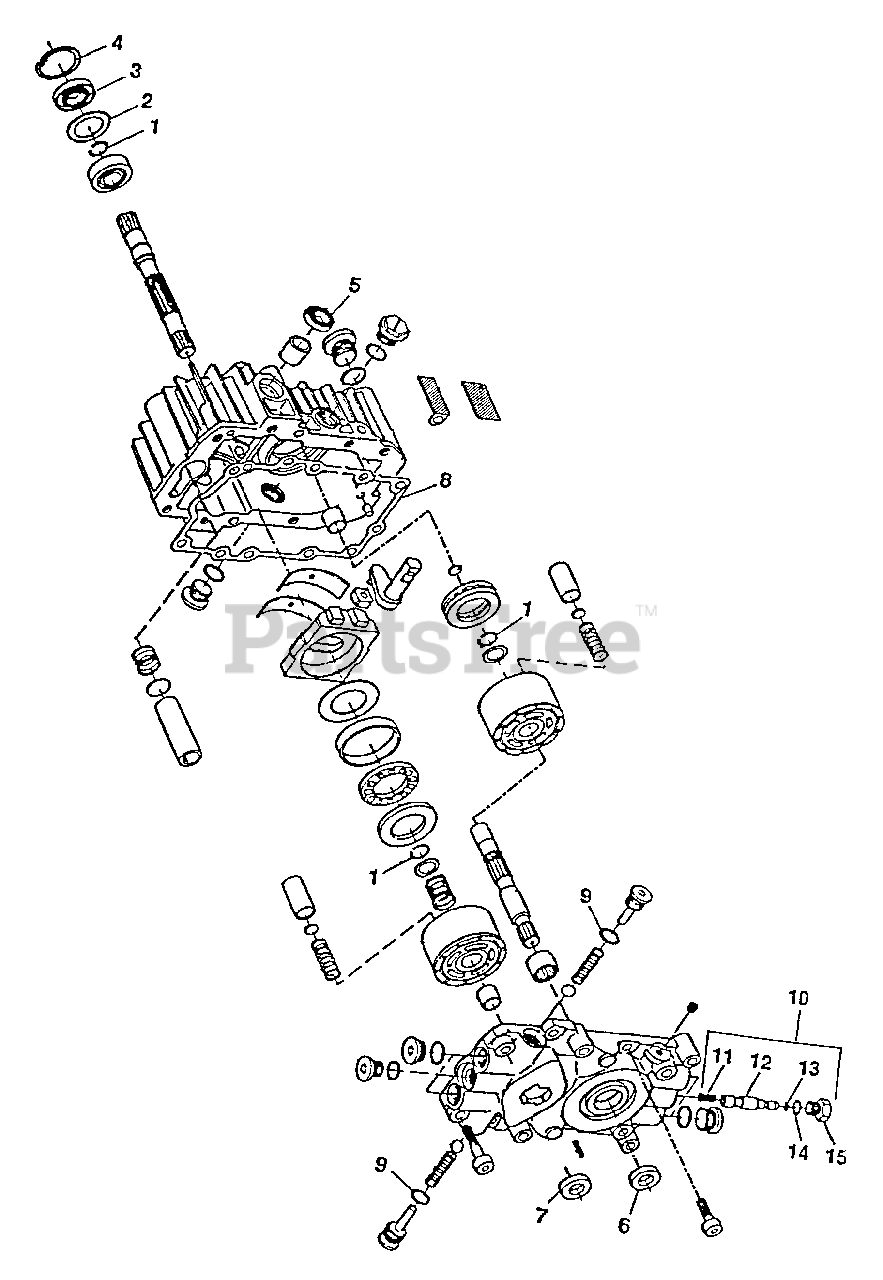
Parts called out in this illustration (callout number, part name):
1	RING-RETAINING
2	SPACER
3	SEAL-LIP
4	RING-RETAINING
5	SEAL-LIP
6	SEAL-LIP
7	SEAL-LIP
8	GASKET-CENTER SECTION
9	O-RING
10	BY-PASS VALVE KIT COMPLETE
11	SPRING-HELICAL COMP
12	BY-PASS SPOOL
13	O-RING
14	O-RING
15	PLUG-BY-PASS
